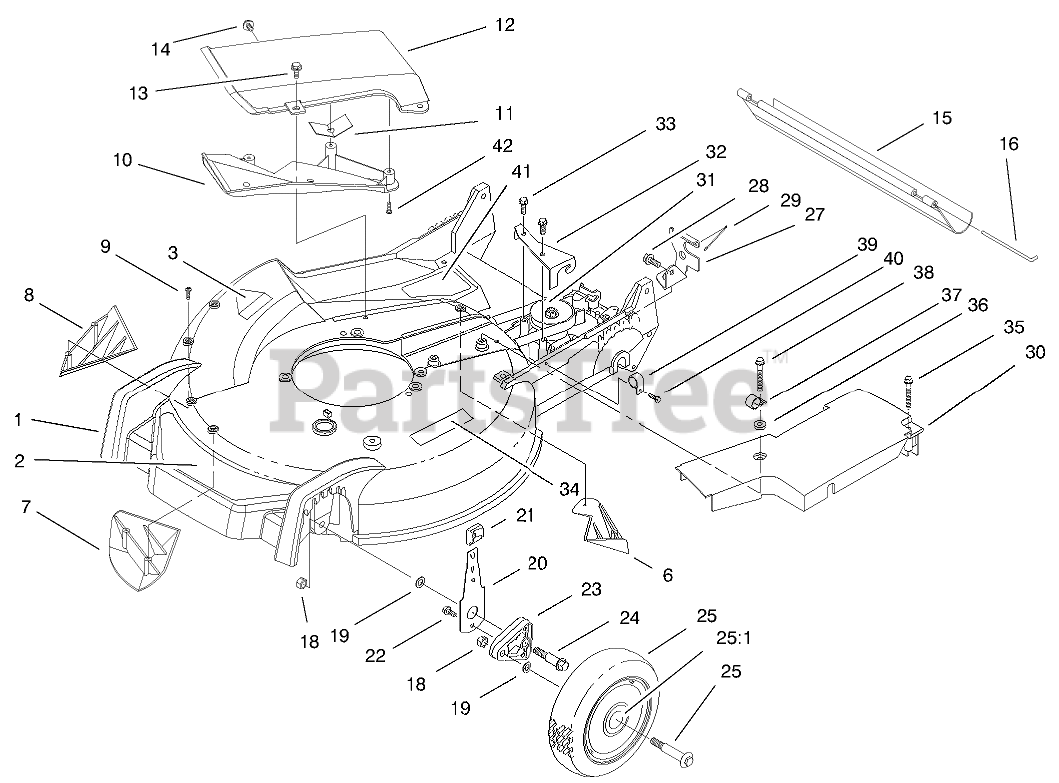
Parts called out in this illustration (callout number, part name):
1	HOUSING
2	DECAL - DECK
3	DECAL-DANGER
6	KICKER-REAR
7	KICKER-FRONT
8	KICKER-RH
9	SCREW-PPH
10	Deflector-Recycler
11	Guard-Cover
12	COVER W/DEFLECTOR
13	SCREW-HWH
14	SCREW AND WASHER ASM
15	SHIELD-TRAILING
16	ROD-SHIELD
18	NUT-LOCK
19	WASHER
20	FRONT SPRING ARM ASM
21	KNOB-ARM
22	SCREW-HWH
23	ARM-PIVOT, FRONT
24	BOLT-SHOULDER
25	WHEEL AND TIRE ASM
25:1	BUSHING
26	BOLT-WHEEL
27	Bracket-Adj. Trac
28	SCREW-HWHTF
29	RETAINER-CABLE
30	COVER-BELT
31	GEARCASE ASM
32	Bracket-Guide
33	SCREW-HWHTF
34	DECAL-WARNING
35	SCREW-HHFTF
36	WASHER
37	CLAMP-CABLE
38	SCREW-SPECIAL
39	CLAMP-CABLE
40	SCREW-HWH
41	DECAL - DANGER
42	Screw-PPH
